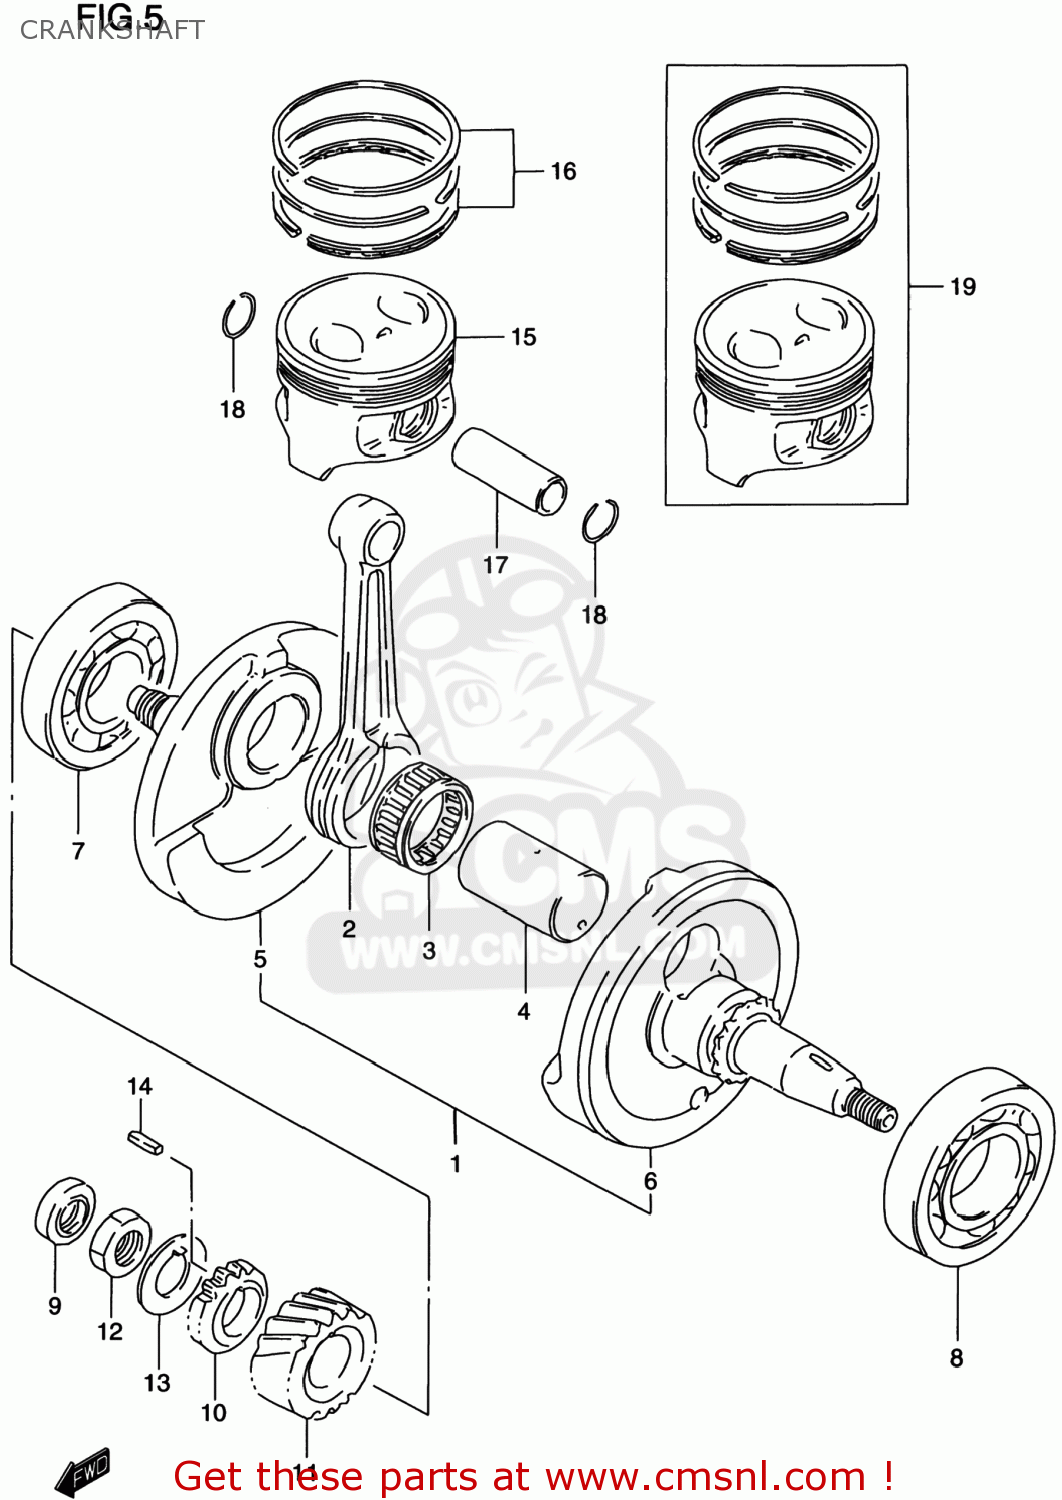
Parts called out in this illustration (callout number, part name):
1	CRANKSHAFT ASSEMBLY
2	CONNECTING ROD
3	BEARING(31X38X18)
4	PIN,CRANK
5	CRANKSHAFT,R
6	CRANKSHAFT,LEFT
7	BEARING(28X68X18)
8	BEARING(35X72X17)
9	SEAL,OIL(12X21X7)
10	GEAR,OIL PUMP DRIVE(NT:15)
11	GEAR,PRIMARY DRIVE
12	NUT
13	WASHER
14	KEY
15	PISTON (66.00MM)
16	RING SET,PISTON
17	PIN,PISTON
18	RING,SNAP 16MM
19	PISTON SET (OS:0.5)
20	RING SET,PISTON(OS:1.0)
